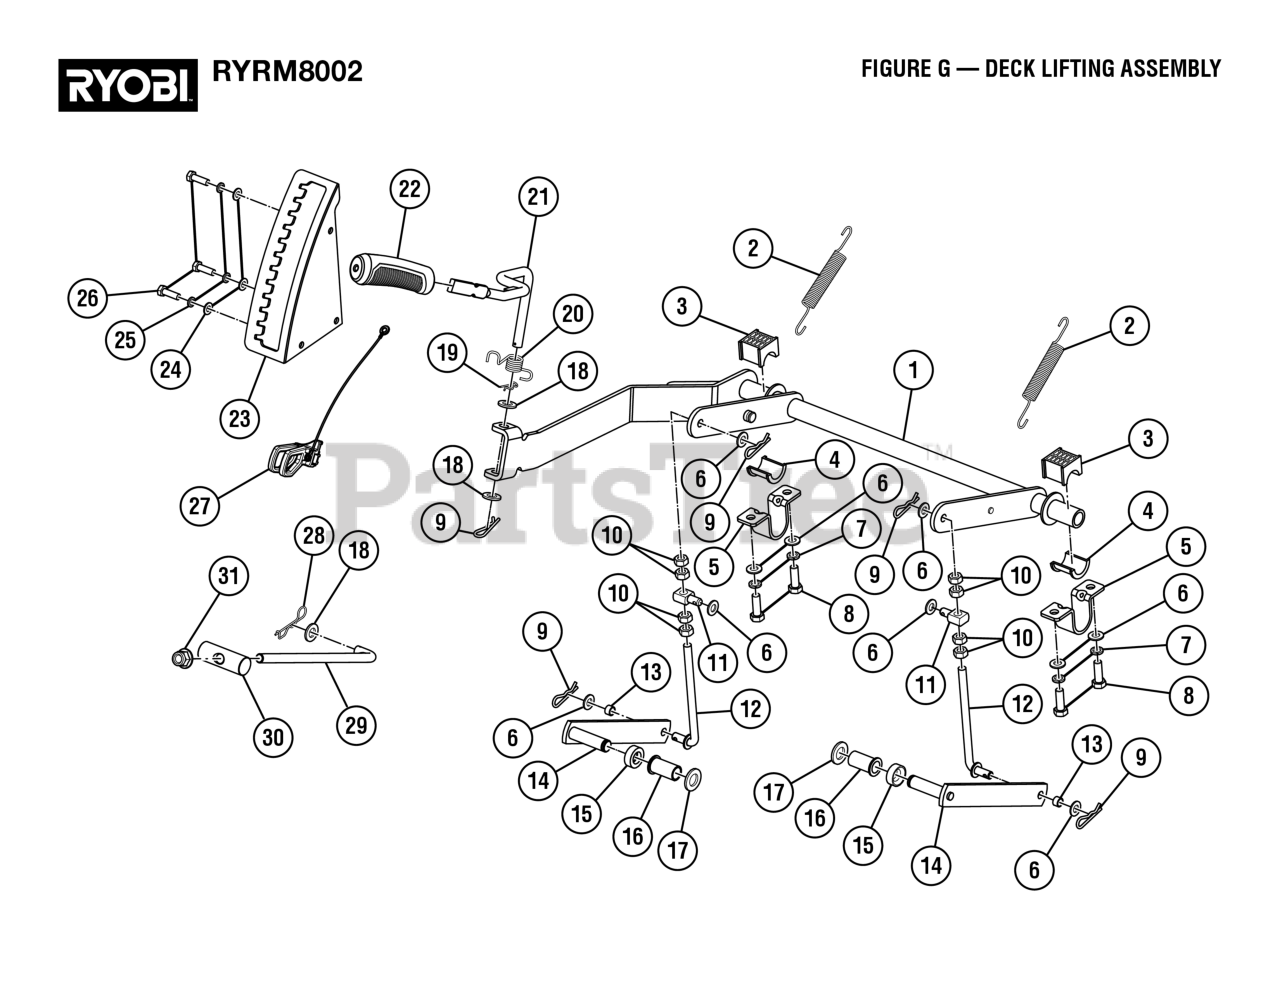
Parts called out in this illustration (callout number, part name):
1	Deck Lift Linkage and Axle Assembly
2	Deck Lift Spring
3	Deck Lift Axle Bushing,Top
4	Deck Lift Axle Bushing, Bottom
5	Deck Lift Axle Mount
6	Washer (OD20 x ID10.5 x 2t)
7	Lock Washer (M10)
8	Hex Head (M10 x 30 mm)
9	Cotter Pin
10	Nut (M10)
11	Hanger Stud, ZTR
12	J Hook, Deck Hanger
13	J-Hook Bushing
14	Deck Lift Linkage
15	Deck Lift Linkage Spacer
16	Deck Lift Linkage Bushing
17	Washer (OD30 x ID17 x 3t)
18	Washer (OD24 x ID13 x 2.5t)
19	Cotter Pin (12 mm)
20	Deck Lift Lever Torsion Spring
21	Deck Lift Lever
22	Decklift Handle
23	Detent Plate
24	Washer (OD16 x ID8.4 x 1.6t)
25	Lock Washer (OD9.8 x ID8.5 x 5t)
26	Bolt (M8 x 25 mm, Hex Hd.)
27	Cut Height Memory Plug
28	Hinge Cotter Pin
29	Front Deck Hook
30	Front Deck Hanger Pivot Axle
31	Flange Nut (M12)
